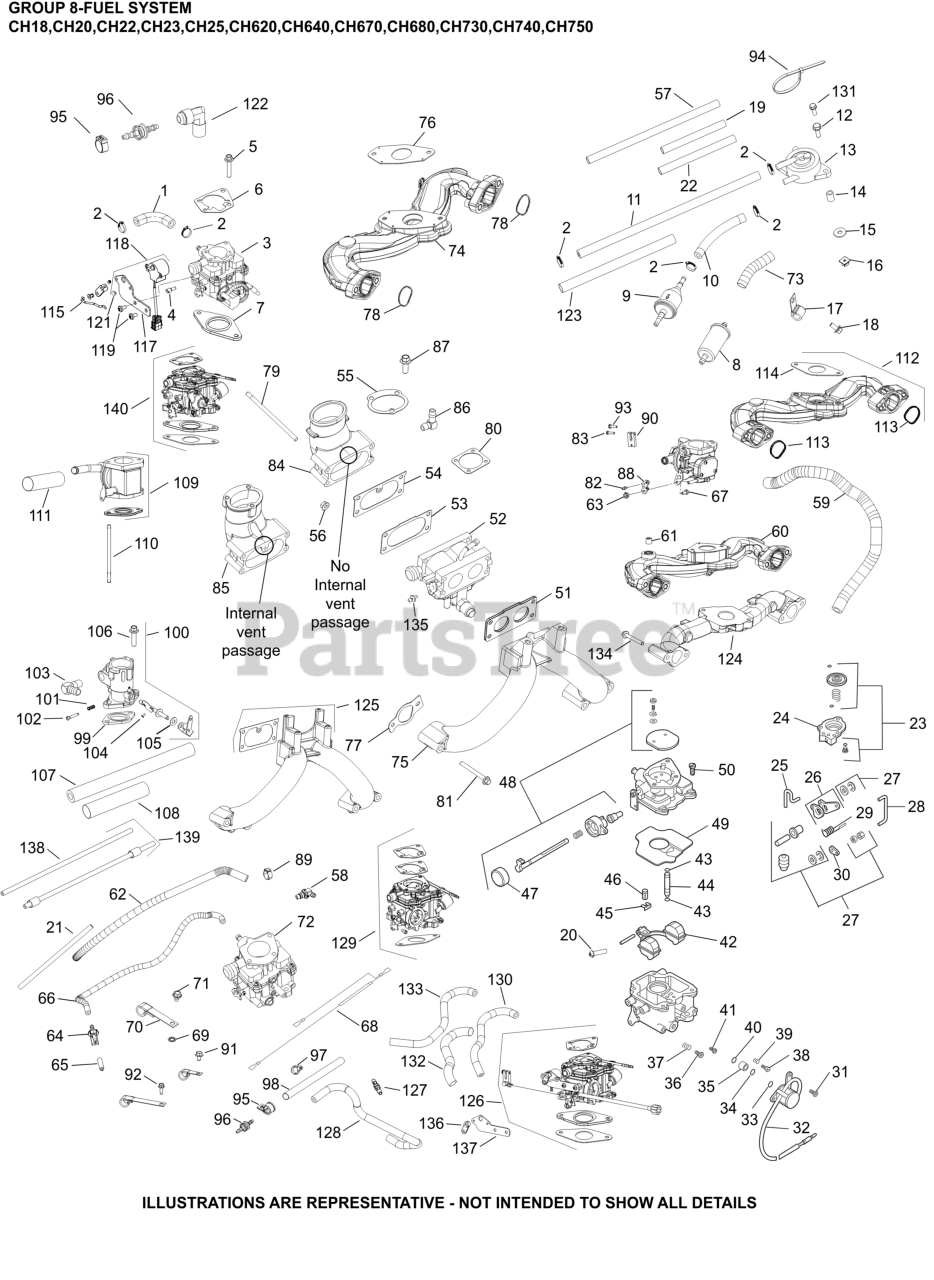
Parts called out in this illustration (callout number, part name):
1	HOSE,LW PERM.FUEL 24.00"-USE 25 111 81-S
3	KIT, CARBURETOR COMPLETE
7	GASKET, CARBURETOR
9	FILTER, FUEL
32	KIT, SOLENOID
42	KIT, REPAIR FLOAT
48	KIT, REPAIR CHOKE
64	CONNECTOR, EVAPORATIVE
65	CAP, MASKING
66	HOSE, EVAPORATIVE 20"- (#24326143S)
77	KIT, INTAKE MANIFOLD GASKET
124	MANIFOLD, METAL INTAKE
134	SCREW, HEX FLANGE
NI	KIT, HIGH ALT (4000-8000 FT)
NI	KIT, HIGH ALT (8,000+ FT)
NI	KIT, REPAIR CARBURETOR
